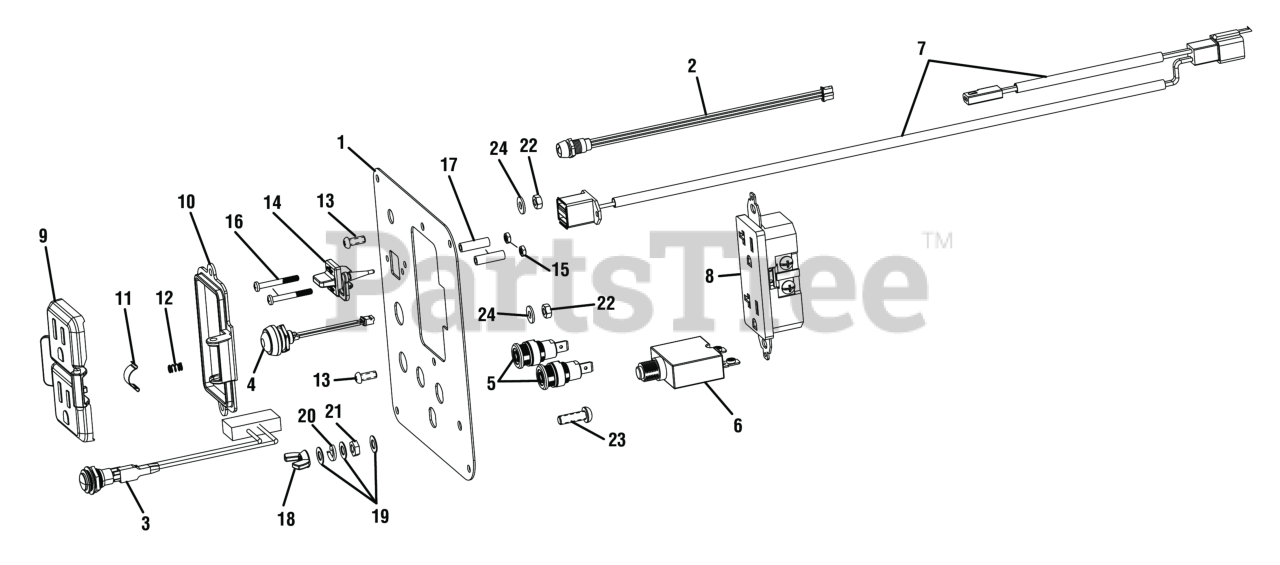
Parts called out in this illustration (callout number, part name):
1	Faceplate
2	CO Indicator
3	Overload Reset Button
4	Auto Idle Button
5	Connector (Black)
6	Circuit Breaker (20 Amp, 125 Volt)
7	Regulator Wire Harness w/USB Ports
8	120 Volt Duplex Receptacle (BM903611)
9	Receptacle Cover (Front)
10	Fixed Outlet Cover
12	Governor Damping Spring
13	Bolt (M4 x 10 mm, T15 Torx Drive Hd.)
14	Dual USB Cover
15	Hex Nut (M3)
16	Screw (M3 x 25 mm, Phillips Pan Hd )
17	Spacer (17.2 mm)
18	Wing Nut (M5)
19	Flat Washer (OD10 x ID5.3 x 0.5t)
20	Lock Washer (OD9 x ID5 x 1.3t)
21	Hex Nut (M5)
22	Flange Nut (M4)
23	Screw (M5 x 16 mm, Phillips Pan Hd.)
24	Flat Washer (OD10 x 42 x 1t)
